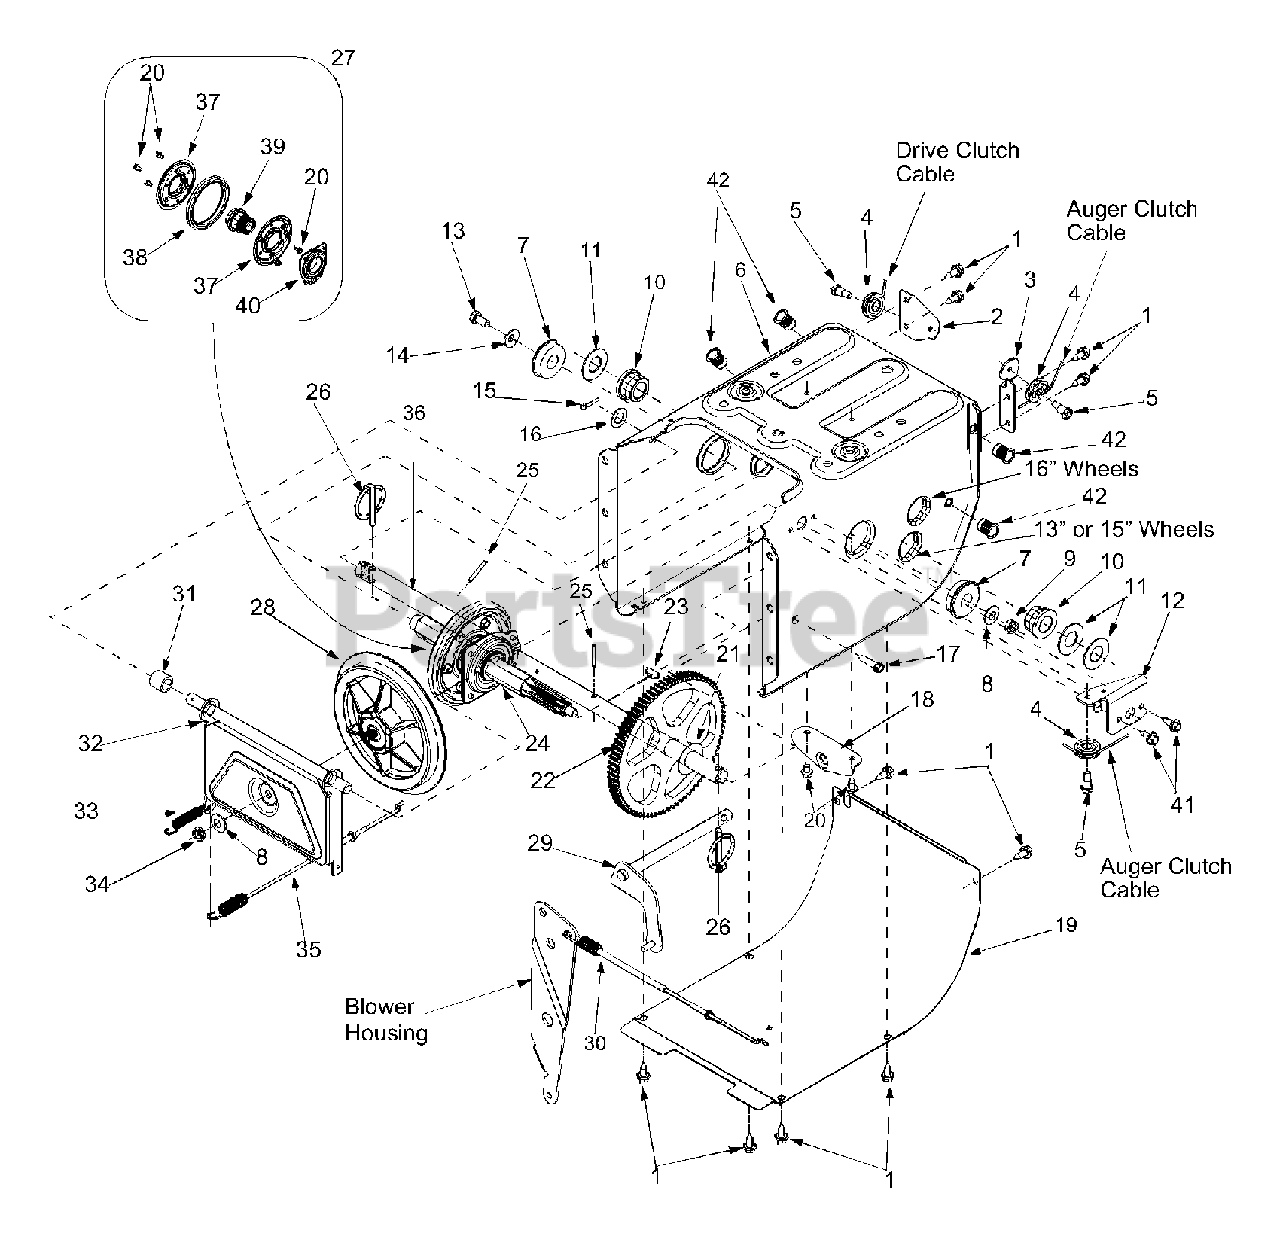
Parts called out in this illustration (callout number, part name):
1	Hex Screw
5	Hex Screw 1/4-28
8	Bell Washer
9	Lock Jam Nut
10	Hex Flange Bearing
11	Flat Washer
14	Bell Washer .340 ID x .872 OD
15	Cotter Pin
16	Flat Washer .536 ID x .930 OD
17	Hex Washer Screw 1/4-20
21	Flat Washer .760 ID x .50 OD
24	7-Tooth Shaft
25	Roll Pin
26	Klik Pin
27	Friction Wheel Assembly
28	Friction Disc Wheel
29	Wheel Shift Rod Assembly
30	Drive Cable, Auger
31	Spacer
34	Jam Nut 3/8-24
35	Drive Cable, Clutch
36	Axle 13" Wheels
36	Axle 16" Wheels
37	Friction Plate
38	Friction Wheel Rubber
39	Friction Wheel Hub
40	Friction Wheel Bearing
41	Tap Screw 1/4-20
42	Insert Nut 5/16-18
